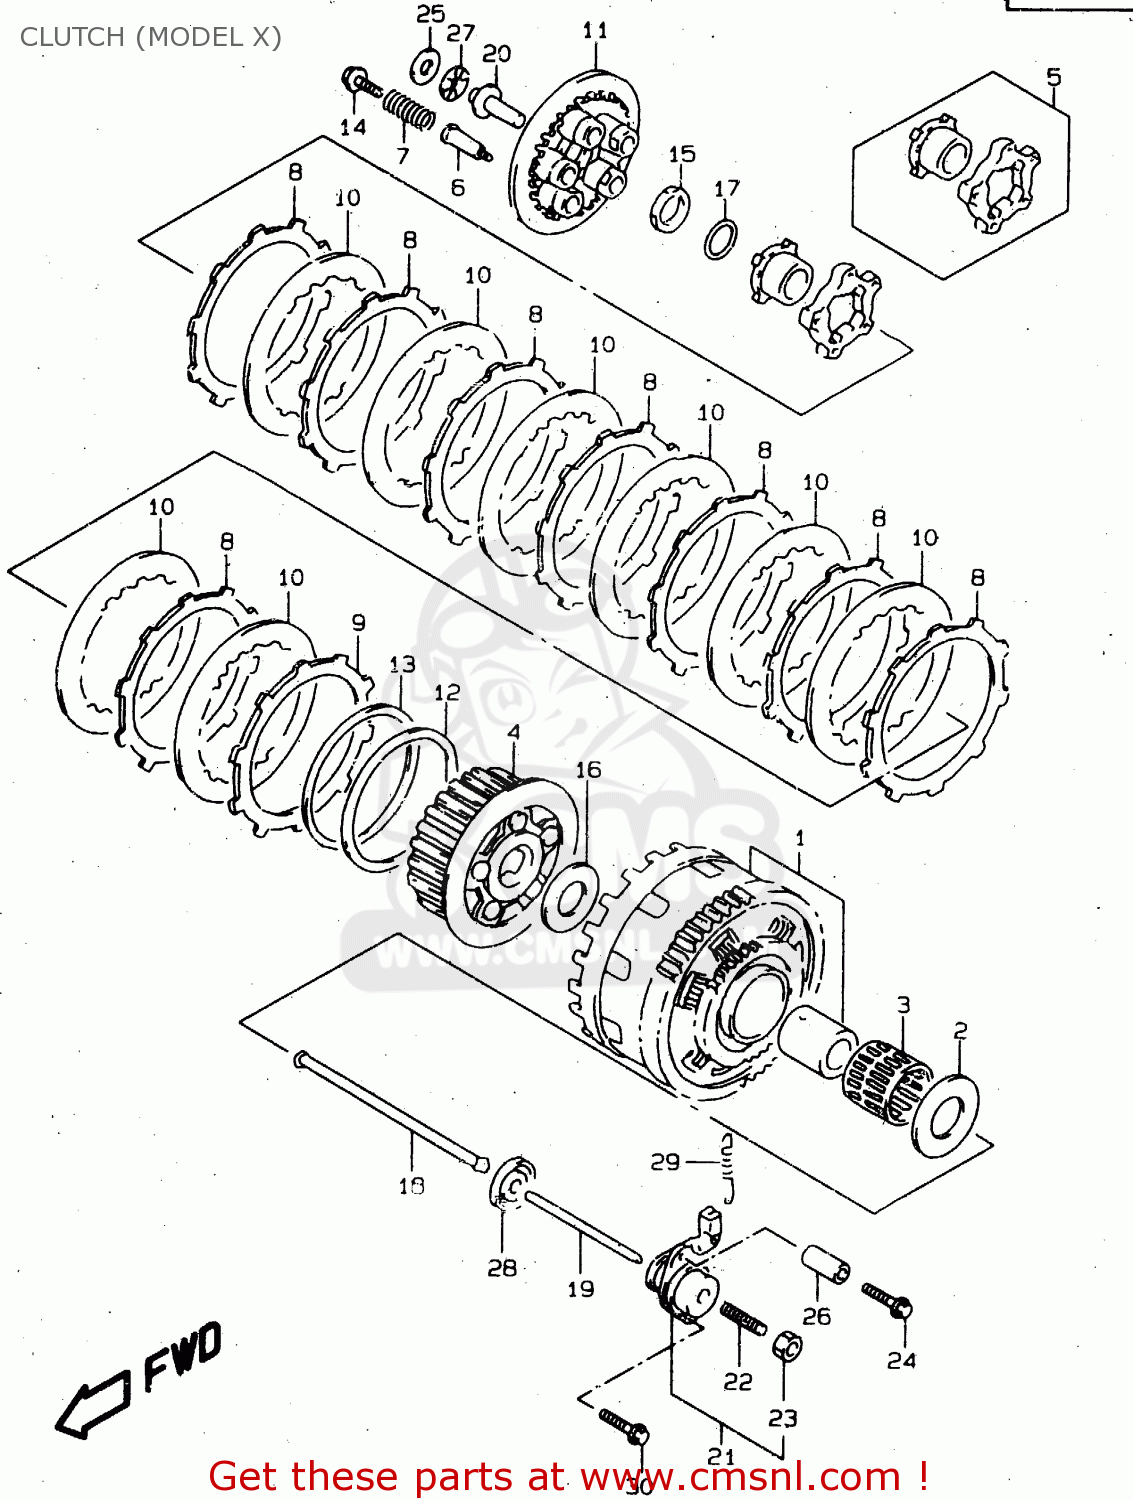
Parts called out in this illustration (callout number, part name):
1	GEAR ASSY,PRI DRIVEN
2	WASHER(25X54X2.5)
3	BEARING(35X40X35.8)
4	HUB,CLUTCH SLEEVE
5	CAM SET,CLUTCH
6	BOLT,SPRING SUPPORT
7	SPRING,CLUTCH
8	PLATE,CLUTCH DRIVE (NAS)
9	PLATE,CLUTCH DRIVE NO (NAS)
10	PLATE,CLUTCH DRIVEN (NAS)
11	DISC,CLUTCH PRESSURE
12	SEAT,WAVE WASHER
13	WASHER,CLUTCH PLATE WAVE
14	BOLT,CLUTCH SPRING
15	NUT
16	WASHER(25X50X2.5)
17	WASHER
18	ROD,CLUTCH PUSH,R
19	ROD,CLUTCH PUSH
20	PIECE,CLUTCH PUSH
21	SCREW ASSY,CLUTCH RELEASE
22	SCREW(6X25)
23	NUT
24	BOLT
25	WASHER(15.5X28X1)
26	SPACER(6.2X12X50)
27	BEARING(15X28X2)
28	SEAL,OIL(6X34X5.5)
29	SPRING
30	BOLT
